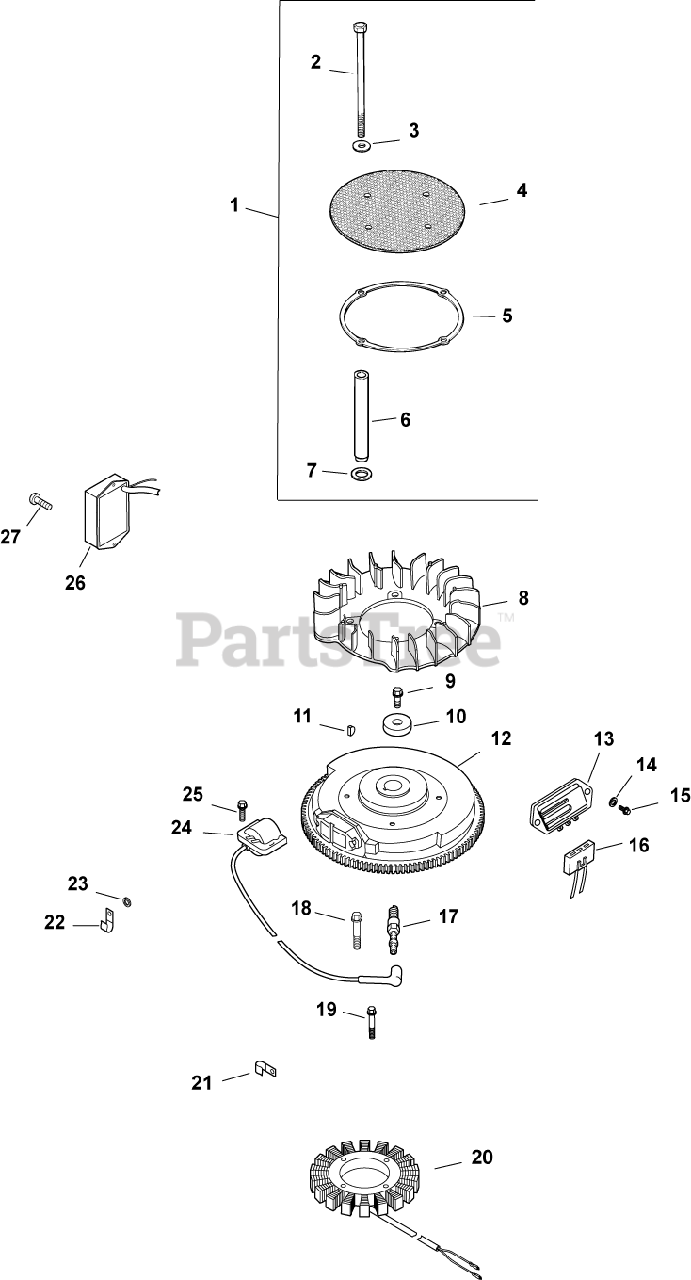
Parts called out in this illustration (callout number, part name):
1	KIT, CHOPPER SCREEN
2	SCREW, CAP M6X1.0X99.5
3	WASHER, FLAT 1/4" (O.D. 5/8")
4	SCREEN, GRASS-USE 24 162 41-S
5	RING, SUPPORT USE 25 141 08-S
7	WASHER, SPRING 10 MM
9	SCREW, FLG M10X1.5X45 - (#25086361S)
10	WASHER, FLAT 13/32"
11	KEY, 3/16" X 5/8"
12	FLYWHEEL ASSEMBLY-USE 24 025 58-S
13	REG/RECT-15 AMP (KM)-USE 41 403 10-S
14	WASHER, FLAT 3/16"
15	SCREW, PHL HD #11-16X7/8"
16	CONNECTOR, BODY (KM)-USE 25 155 41-S
17	PLUG, SPARK (STD)
18	SCREW, M5X0.8X25 - (#25086402S)
19	SCREW, SKT SET #10-24X1/4"
20	KIT, 15 / 20 AMP STATOR
21	CLIP, TUBE & WIRING (KM)
22	CLIP, CABLE
23	WASHER, FLAT 1/4" (O.D. 1/2")
24	MODULE, IGNITION
25	SCREW, FLG THD FRM M5X.8X20-(#25086399S)
26	MODULE, SPEED ADVANCE -USE 24 755 162-S
27	SCREW, THD FRM M4X0.7X10
